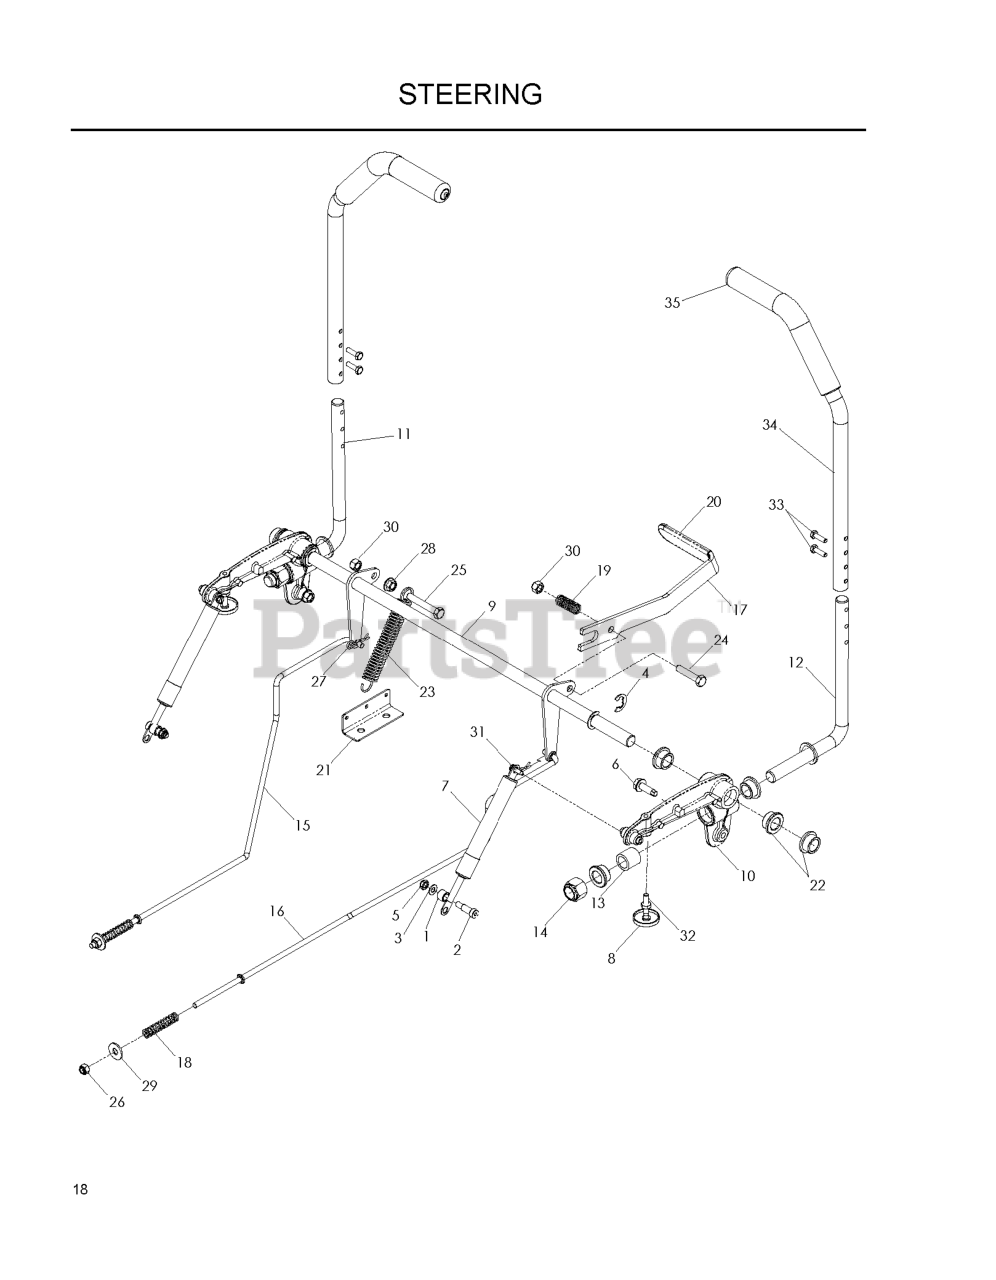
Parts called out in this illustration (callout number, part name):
2	SCREW, 5/16 X 5/8 SHOULDER
4	E-RING 5/8
5	JAM NUT 1/4C (2 2 PW01)
6	BOLT 5/16-18 X 1 1/4 TFS
8	POST, RETURN TO NEUTRAL
9	SHAFT, MOTION, BRAKE PLATED
10	MOTION CASTING
11	MOTION CONTROL ARM, WLDMNT LH
12	MOTION CONTROL ARM, WLDMNT RH
13	BUSHING ELASTOMER
14	NUT 5/8-11 NYLOC
15	BRAKE ROD FORMED RT
16	BRAKE ROD FORMED LT
17	BRAKE LEVER
19	BRAKE LEVER SPRING
20	BRAKE LEVER CAP
21	SPRING BRACKET
22	MOTION BUSHING
23	SPRING-TRANS
24	CAPSCREW 5/16 X 1/1/2 HEX HEAD
25	HCS 5/16-18X2
26	NUT.1/4-20.HEX.NYLOC.ZD
27	HAIRPIN #2
28	NUT 5/16C WHIZ
29	WASHER 5/16 FLAT
30	NUT 5/16 NYLOC
31	SCREW #10 X 1/2 SELF TAPPING
32	NUT 1/4-20 JAM
33	HCS 1/4-20X7/8 GR5
34	CONTROL LEVER
35	CONTROL LEVER CUSHION
